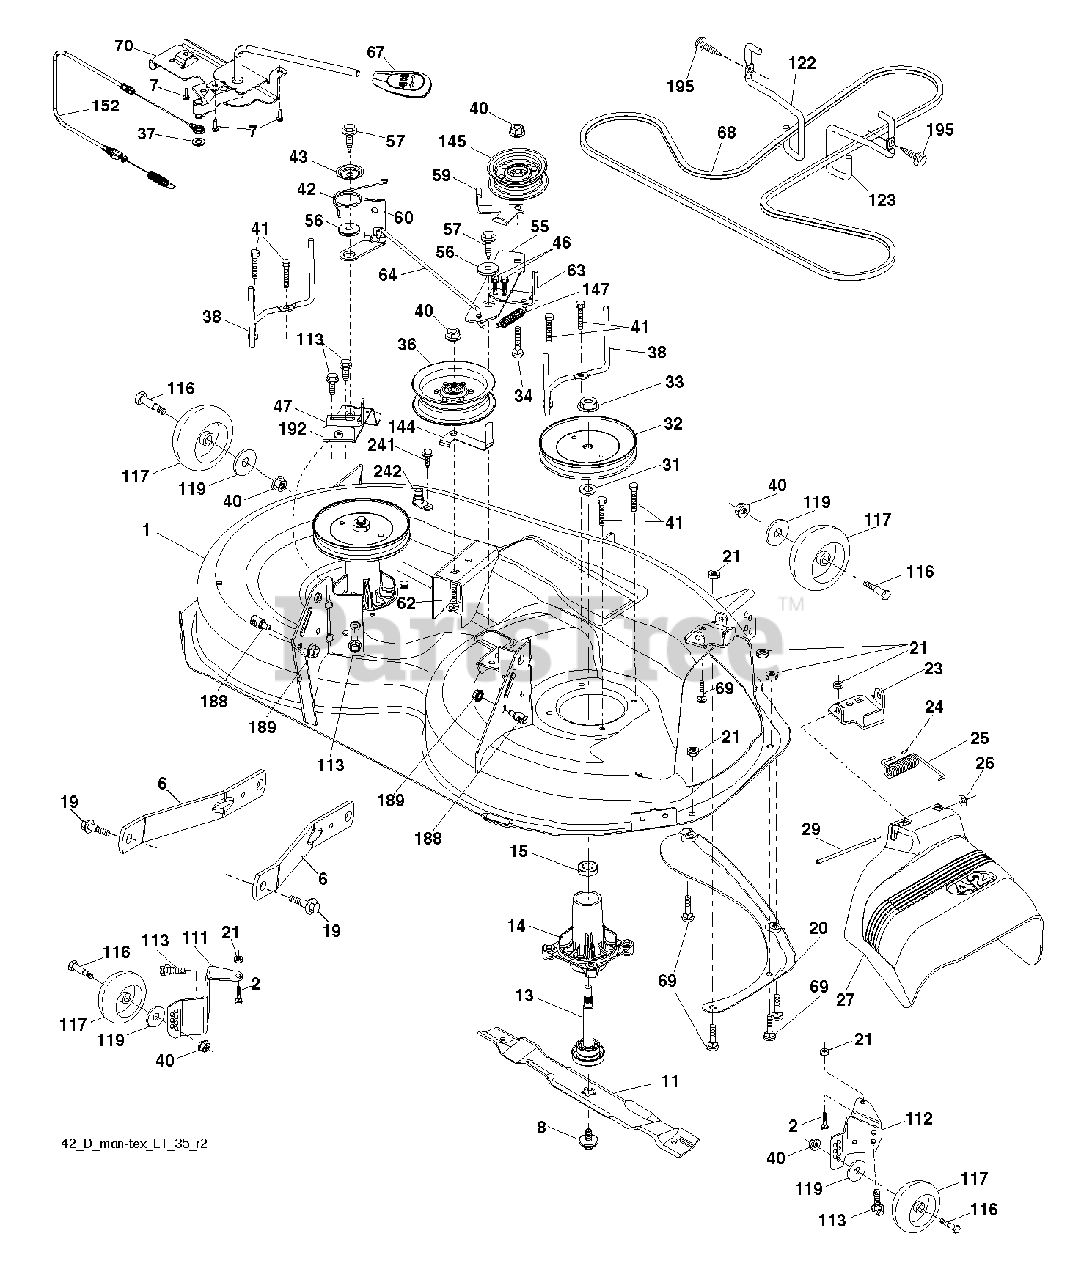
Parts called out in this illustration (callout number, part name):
2	BOLT
6	ARM.SUSPENSION.MOWER.R
7	SCREW.#10 X 0.750.BOS THREAD
8	BOLT.WASHER.ASM.7/16-2
11	42" HI-LIFT BLADE
13	SHAFT.ASM.MDRL.N/GREASE.38
14	HOUSING MANDREL
19	BOLT.SHOULDER
20	BAFFLE.VORTEX
21	LOCKNUT
23	BRKT.DEFLECTOR.38"2005+
24	CAP-SLEEVE LT
25	SPRING.TORSION.DEFLECT
26	NUT PUSH M
27	SHIELD.DEFLECTOR.MOWER.42"BLAC
29	ROD.HINGE
31	WASHER.SPACER.MANDREL
32	PULLEY.MANDREL.5.438.PD
33	NUT.FLANGE.LOCK.TOP
34	BOLT.3/8-16X1.50
36	PULLEY.IDLER.2006
38	KEEPER.BELT.MANDREL.PULLEY
40	NUT LOCK FLG 3/8-16 UNC
41	Hex Washer Head Bolt, .313-18 X 1.19
42	SPRING.TORSION.BRAKE
43	SRPING.TORSION.RETAINE
46	SCREW.1/4-20X5/8
47	BRKT.CLUTCH.CABLE
55	IDLER.ARM.42"
56	SPACER.RETAINER
57	SCREW 3/8-16X1
59	GUARD, BELT
60	ARM BRAKE MOWER
62	BOLT
63	ARM BRAKE MOWER
64	LINK BRAKE
67	HANDLE.CLUTCH.CABLE.LT
68	BELT.DECK.DRIVE.42"
69	BOLT
70	CLUTCH.ASM.MANUAL.YT.PREDATORQ
111	BRKT.WHEEL.GAUGE.LH.42"
112	BRKT.WHEEL.GAUGE.RH.42"
113	BOLT.5/16HEX.WHS.HD
117	WHEEL.GAGE.HALF.SPOKED
119	WASHER
122	KEEPER BELT ENGINE LH
123	KEEPER BELT RH
144	KEEPER.BELT.MOWER
145	PULLEY.IDLER.48"PRIMARY
147	RETURN SPRING
152	Mechanical Clutch Cable
188	STUD.FASTNER.W/ANTI-ROTATE
189	NUT LOCK HEX FLANGE 5/16-18
192	BRKT.BRAKE.STAND.LH.
195	SCREW
242	PORT.WASHOUT
